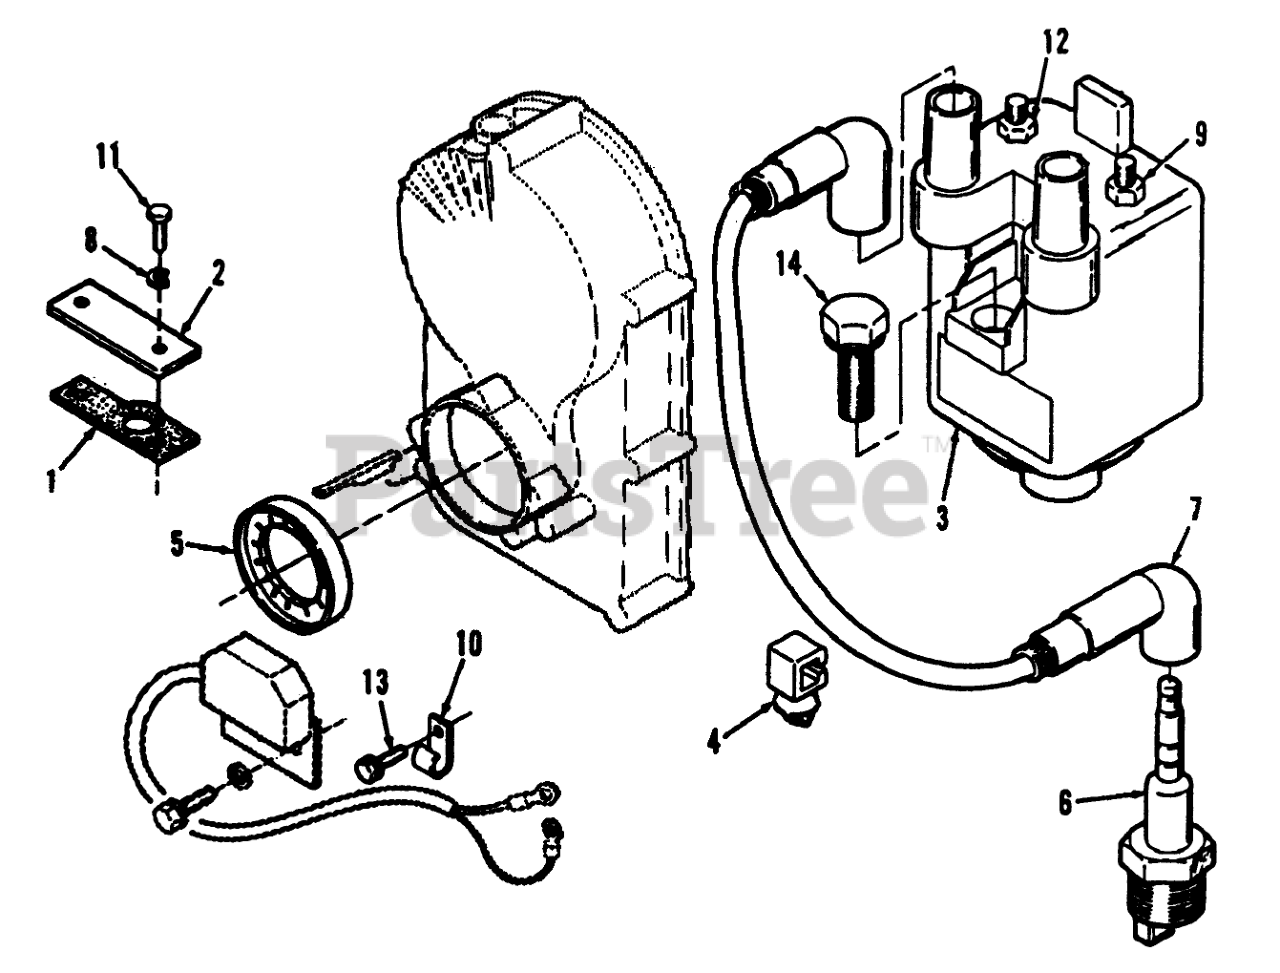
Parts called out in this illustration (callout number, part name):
1	Gasket-Plate
2	Plate
3	Coil-Battery Ignition (Includes Nuts)
4	Clip
5	Rotor
6	Plug-Spark
7	Wire-Plug
8	WASHER-FLAT
9	Nut
10	Clip
11	SCREW - CAP HEX HEAD
12	Nut
13	Bolt
14	Bolt
